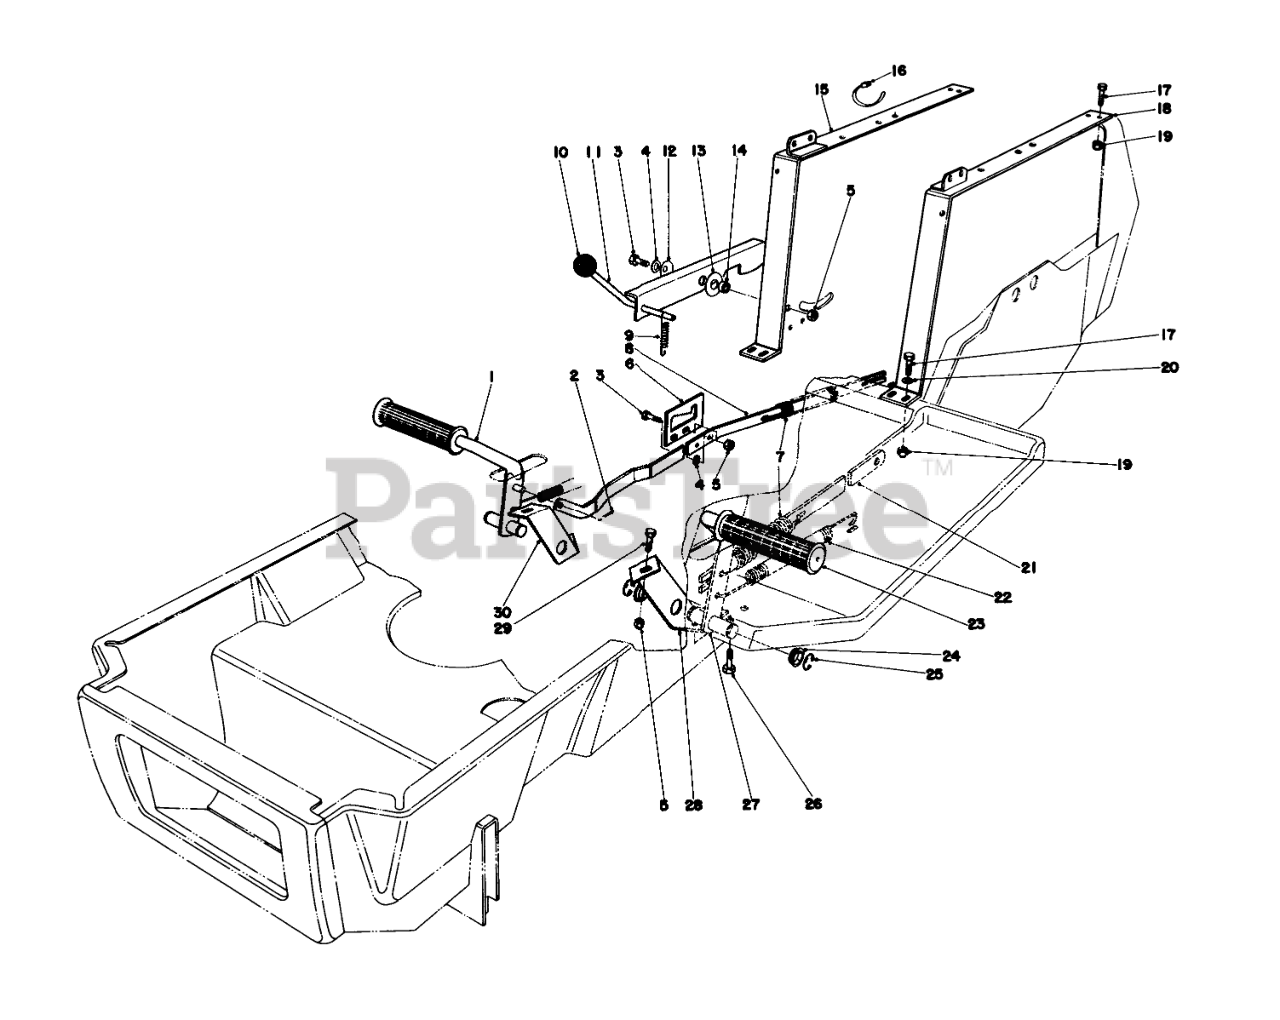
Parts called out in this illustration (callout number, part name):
1	BRAKE PEDAL WA BO
2	PIN-COTTER
3	SCREW-HH
4	WASHER-PLAIN
5	NUT-LOCK, CONE
6	LATCH PLT-BRAKE ROD
7	EXT SPRING O
8	LINK BRAKE ROD WAB
9	CONT ROD SPRING 0
11	PARKING BRAKE WA B
12	Belleville Washer
13	WASHER-PLASTIC
14	SPACER
15	Strap-Rear Body R.H.
16	TIE-CABLE
17	SCREW-HH
18	Sheave
19	NUT-LOCK, CONE
20	WASHER-FLAT
21	CLUTCH ROD LINK B
22	SPRING-EXTENSION
23	FOOT PAD
24	Nyliner
25	E-RING
26	SCREW-HWHTF
27	CLUTCH PEDAL WA BO
28	LH PEDAL SUPT B
29	SCREW-HH
30	RH PEDAL SUPT B
